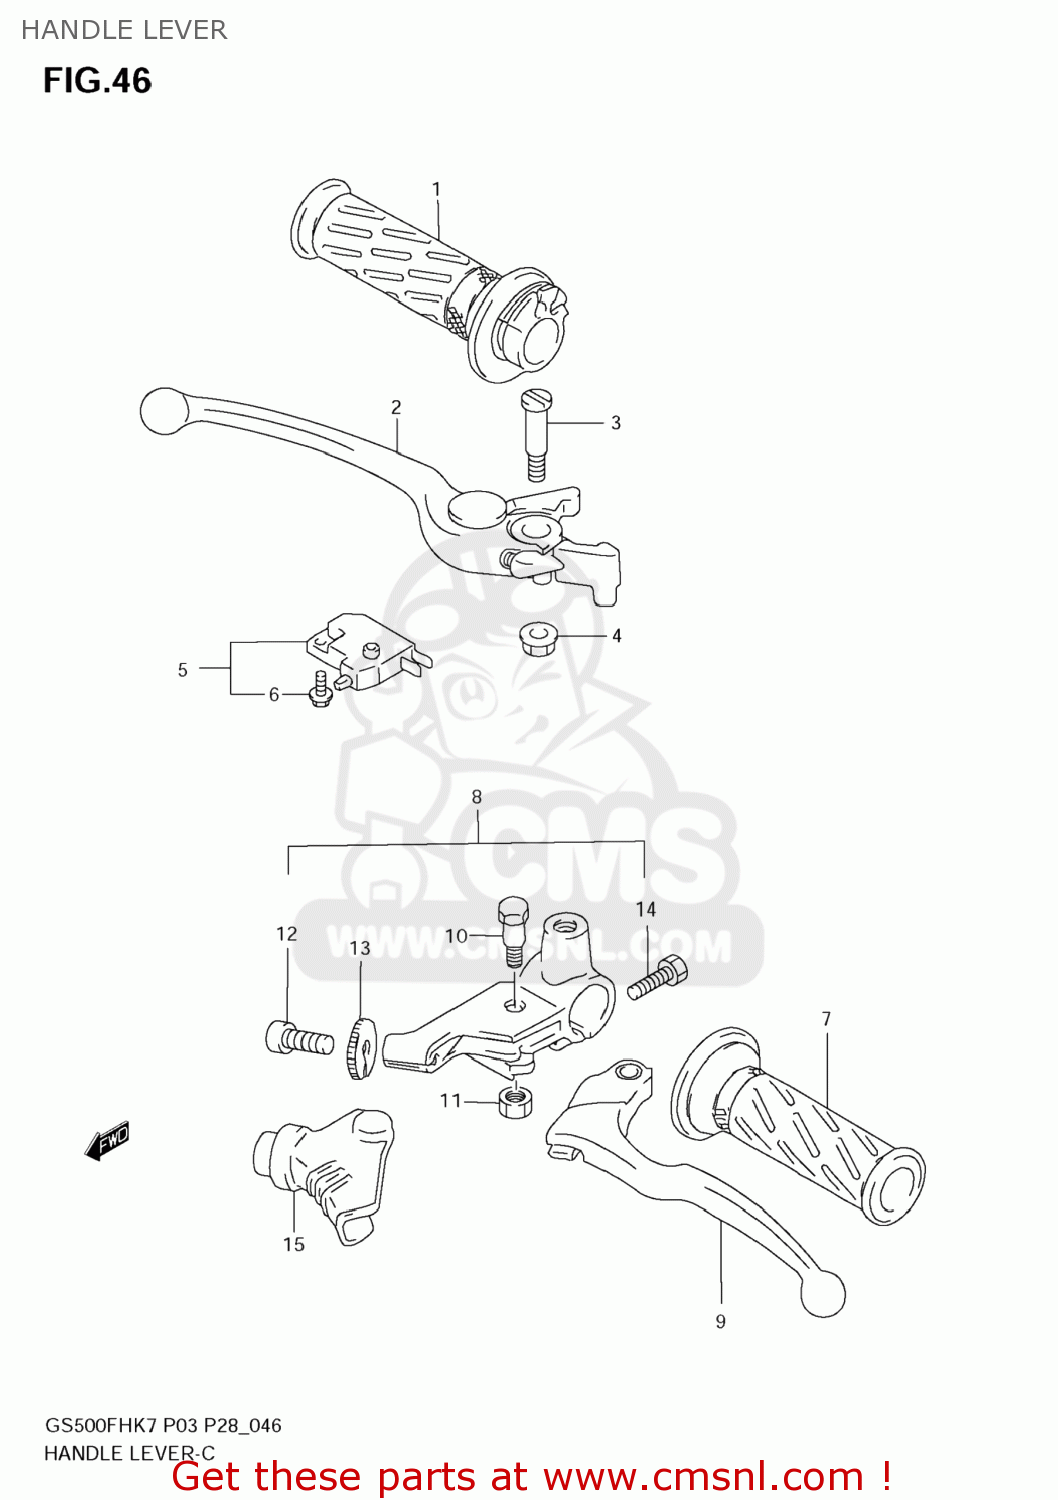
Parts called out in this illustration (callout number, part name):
1	GRIP, THROTTLE
2	GRIP, BRAKE
3	BOLT, PIVOT
4	NUT
5	SWITCH ASSY,ST
6	SCREW
7	GRIP LH
8	LEVER ASSY,CLUTCH
9	LEVER,CLUTCH
10	BOLT,LEVER SET
11	NUT
12	ADJUSTER,CABLE
13	NUT,CABLE ADJUSTER
14	BOLT
15	COVER,CLUTCH LEVER
